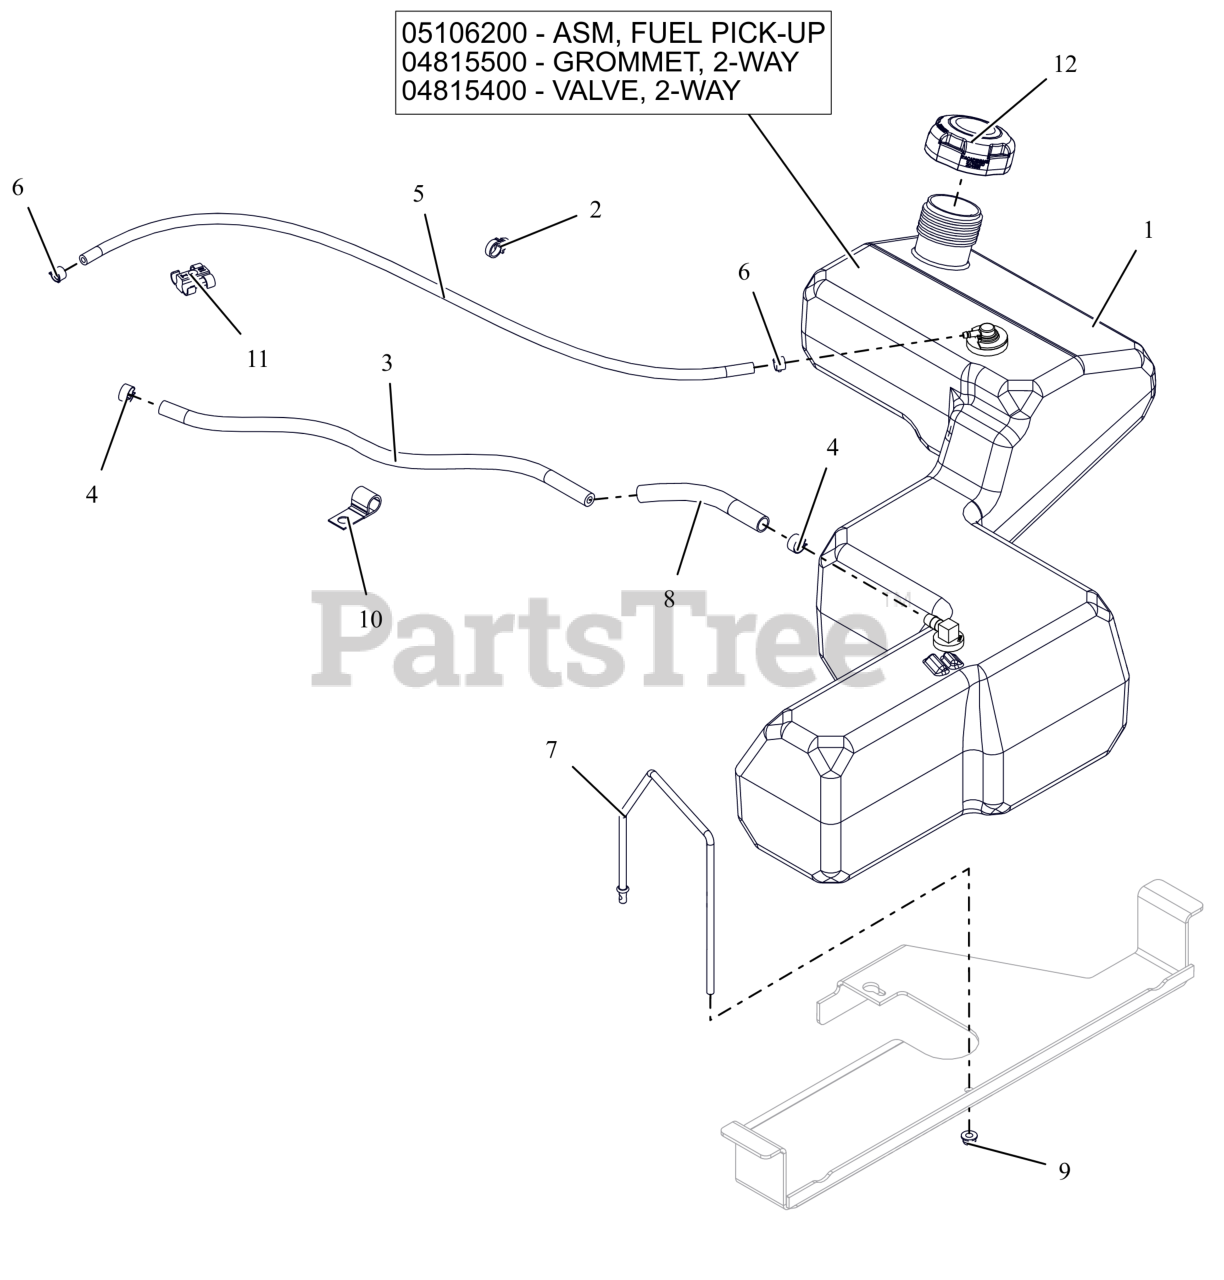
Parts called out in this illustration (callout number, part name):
1	ASM, FUEL TANK-IKON
1	ASM, IKON FUEL PICK-UP
1	GROMMET, 2-WAY
1	VALVE, 2-WAY
2	ROUTING CLIP (1/2" ID)
3	HOSE, .25 LOW-PERM BULK GAS
4	CLAMP, FUEL LINE
5	HOSE, .188 LOW-PERM BULK GAS
6	CLAMP-HOSE, SPRING .188
7	BRKT, FUEL TANK HOLD DOWN
8	WRAP, ANTIABRASION .5X.064WALL
9	NUT,NYL-FLG .25-20 GF ZCC
10	J-CLAMP
11	CLIP, T, .38-.50
12	CAP, FUEL - 2.25 RATCHET INLET VENT
